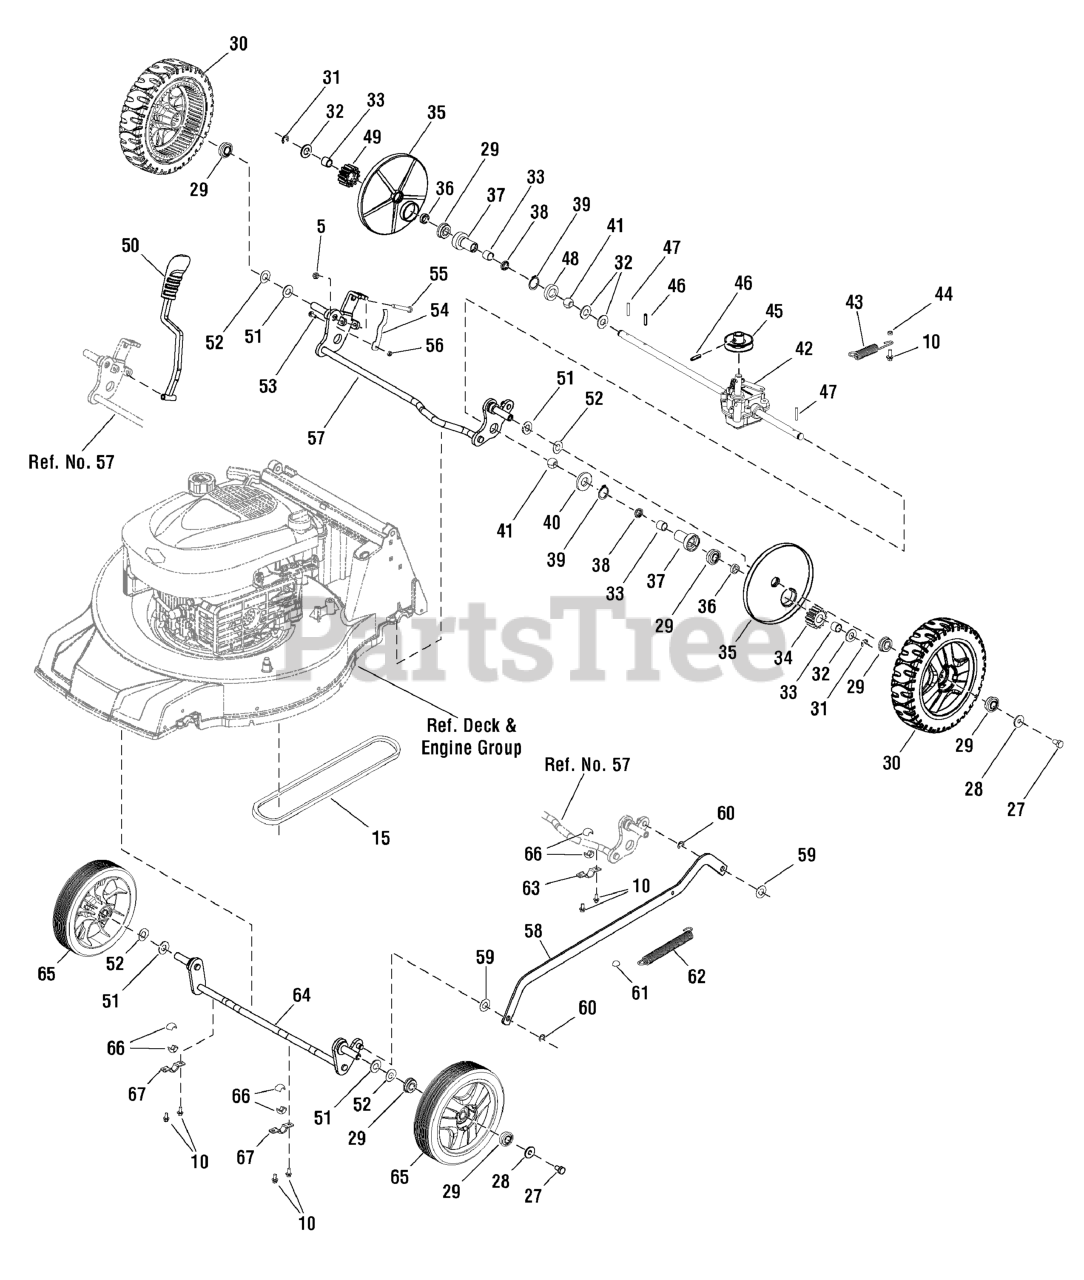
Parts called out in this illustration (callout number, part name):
5	NUT, Hex, Nylon Insert, Torque Type
10	SCREW, Hex Flange, Tapping
15	V-BELT, Normal, V10 × 783 gates
15	V-BELT, Common
28	COVER, Wheel
29	BEARING
30	WHEEL, Rear, Self-Propelled, 8"
30	WHEEL, Rear, Self-Propelled, 9"
31	CHECK RING
32	WASHER, Anti-Friction
33	OIL BEARING B
34	PINION, Left
35	SHIELD, Dust, Rear
36	SPACER, Main Axle
37	BEARING SHEATH
38	RING, Dustproof
39	RING, Elastic, For A-form Axle
40	WASHER, Left Bearing Bracket
41	BALL BEARING, Nylon
42	TRANSMISSION, Single Speed
43	SPRING, Gearbox
45	PULLEY, Gearbox
46	PIN, Elastic Cylindrical
47	PIN, Sliding
48	SPACER, Transmission
49	PINION, Right
50	LEVER, Height Adjust
51	WASHER, Wheel Axle
52	WASHER, Spring
53	BOLT, Hexangular, Full Thread
54	SPRING, Armature
55	BOLT, Hexangular
56	NUT, Hex, Nylon Insert, Torque Type
57	AXLE, Rear
58	CONNECTING ROD
59	WASHER, Nylon
60	CHECK RING
61	CHECK CAP
62	SPRING, Connecting Rod
63	BRACKET, Upper Ball Bearing
64	AXLE, Front, 19"
64	AXLE, Front, 21"
65	WHEEL, Front, 8"
66	BALL BEARING
67	BRACKET, Front Ball Bearing
